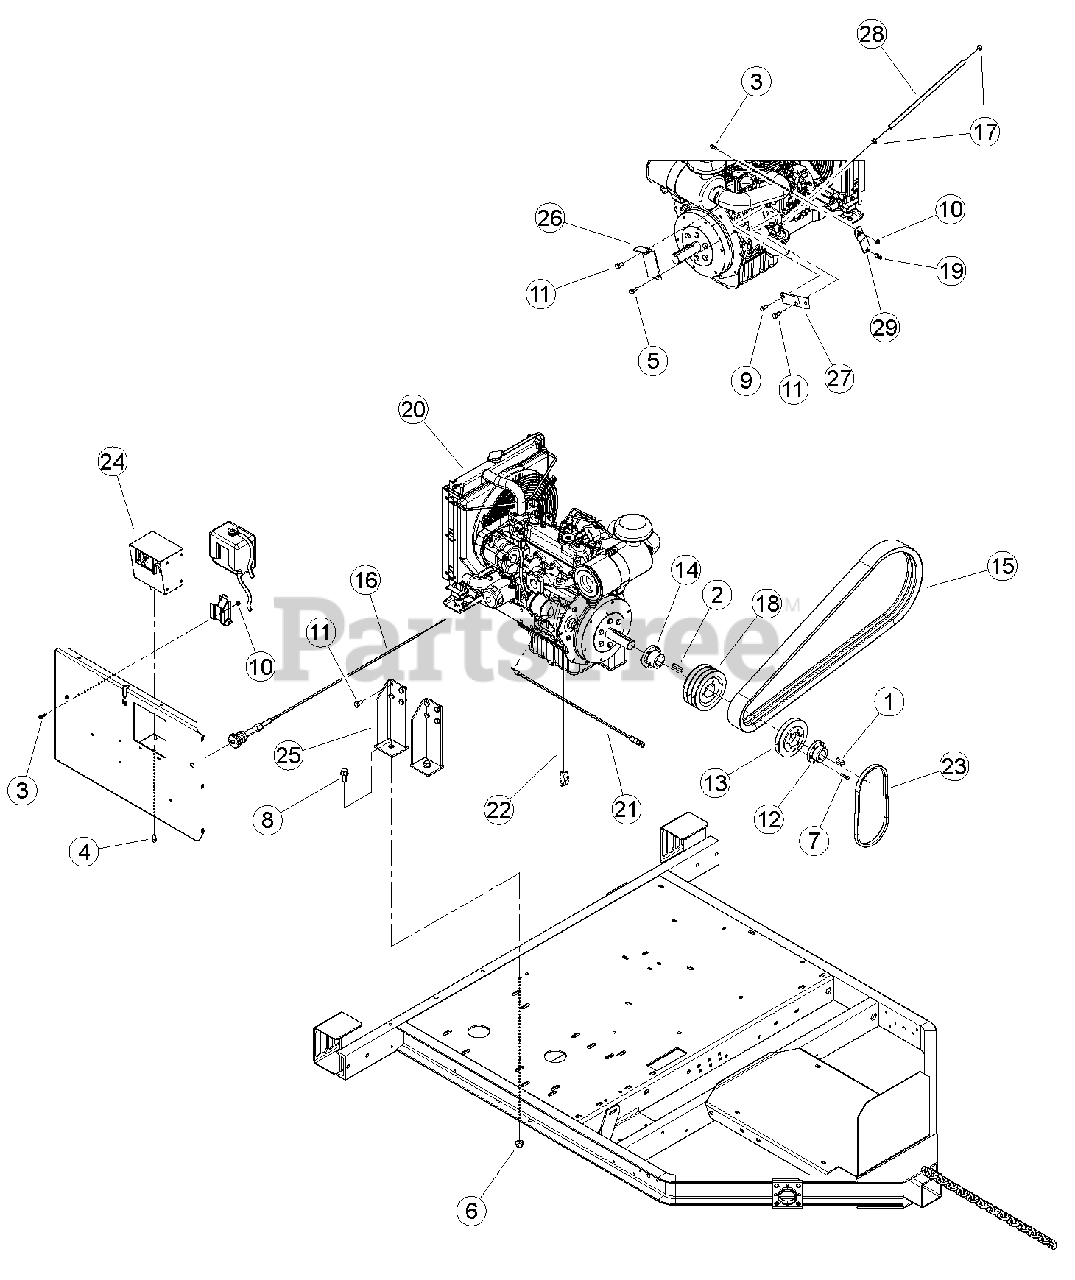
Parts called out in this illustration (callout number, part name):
1	KEY, 3/8 SQ X 1-1/4
2	KEY, 3/8 SQ 1-3/4
3	BOLT, 1/4-20X3/4,HWH,GR5,CZP
4	BOLT, 5/16 X 3/4 FLANGE NC
5	BOLT, 5/16 X 1 FLANGE NC
6	NUT, 1/2-13 NYLOCK FLANGE
7	BOLT, 1/4-20 X 1-1/4 GR5 HHCS MAGNI 565 SILVER
8	BOLT, 1/2 -13 X 1-1/4 FLANGE NC
9	BOLT, M 8-1.25 X 20 GR8.8 HHD ZP
10	NUT, 1/4-20 NYLOCK-FLANGE
11	BOLT, M10 X 1.25 X 20 GR10.9 HEX HEAD ZP
12	BUSHING, SDS 1-7/16"
13	SHEAVE, 1B5.2 SDS
14	BUSHING, SD 1-7/16"
15	BELT, 3B83 BANDED
16	CABLE, DIESEL THROTTLE
17	CLAMP, 9/16 SPRING
18	SHEAVE, 3BQ5.6, SD
19	CABLE STOP, BOWDEN PIN # 6170
20	ASSEMBLY, 28 HP KUBOTA DIESEL ENGINE (FOR SERVICE SEE ENGINE OWNER'S MANUAL OR YOUR NEAREST KUBOTA INDUSTRIAL ENGINE DEALER)
21	CABLE, 72" POSITIVE BATTERY
22	CABLE, 72" NEGATIVE BATTERY
23	BELT, BX30
24	CONTROLLER, DSE - KUBOTA
25	WELDMENT, ENGINE MOUNT
26	ANGLE, SPRING ANCHOR
27	STRIP, CABLE ANCHOR
28	HOSE, 15 INCH FUEL LINE
29	STRIP, THROTTLE CONTROL
